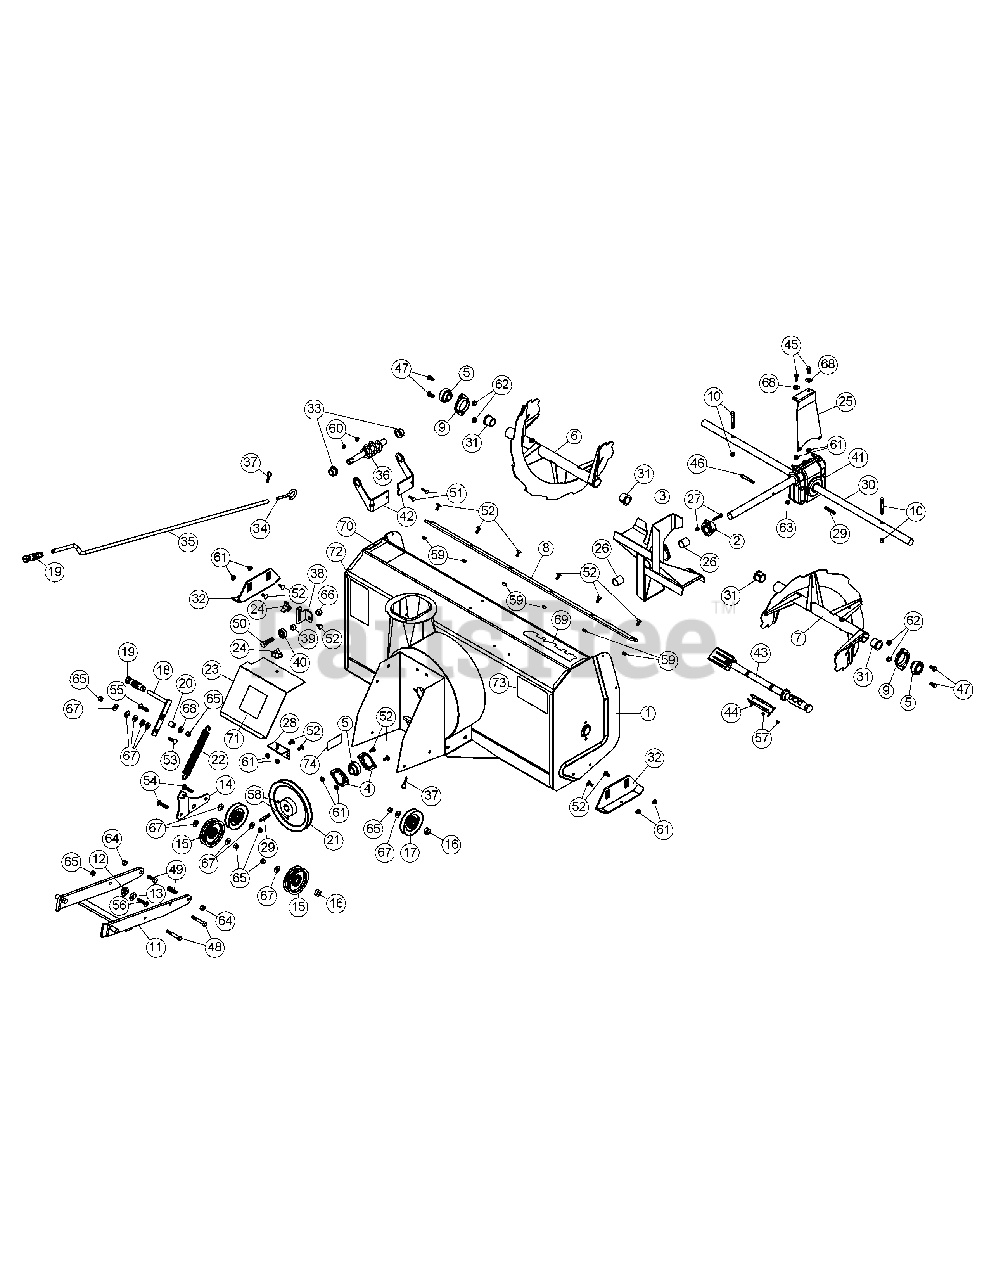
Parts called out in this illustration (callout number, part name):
1	Frame 44"
2	Shear plate
3	Fan
5	Bearing with set screw
6	Auger 44" left
7	Auger 44" right
8	Cutting edge 44"
10	Shear bolt / N.I.L.N. (auger)
11	Male hitch
12	Flange washer
13	Special washer
14	Tension lever
15	Flat pulley
18	Tension arm
25	Gear box support
26	Oil lite bushing
27	Shear bolt / N.I.L.N. (fan)
28	Belt guard support
29	Key 1/4" x 1/4" x 2"
31	Rotation bushing
33	Rotation bushing
34	Handle hook
36	Rotation worm
37	Hair pin 2.5mm
41	Gear box left rotation
42	Worm supports
43	Chute shovel
44	Chute shovel support
45	Hex. bolt 5/16" n.c. x 3/4" GR5
46	Hex. bolt 5/16" n.c. x 2 1/4" GR8
47	Hex. bolt 3/8" n.c. x 3/4" GR5
48	Hex. bolt 3/8" n.c. x 2 1/2" GR5
49	Hex. bolt 7/16" n.c. x 1 1/4" GR5
50	Hex. bolt 1/2" n.c. x 1 3/4" GR5
51	Carriage bolt 1/4" n.c. x 1 " GR5
52	Carriage bolt 5/16" n.c. x 3/4 " GR5
53	Carriage bolt 3/8" n.c. x 1 1/4 " GR5
54	Carriage bolt 3/8" n.c. x 1 3/4 " GR5
55	Carriage bolt 3/8" n.c. x 1 1/2 " GR5
56	Hex socket f.h. cap screw 3/8" n.c. x 1-3/4"
57	Socket Head Cap Screw M5 x 0.80 x 10
58	Socket head set screw 5/16"' n.c. x 5/16''
59	Stover lock nut 5/16" n.c.
60	Flange nut 1/4" n.c.
61	Flange nut 5/16" n.c.
62	Flange nut 3/8" n.c.
63	Nylon Insert lock Nut 5/16" n.c. GR5
64	Nylon Insert lock Nut 7/16" n.c.
65	Nylon Insert lock Nut 3/8" n.c.
66	Nylon Insert lock Nut 1/2" n.c.
67	Flat washer 7/16" hole
68	Flat washer 3/8" hole
69	Decal Cub Cadet
70	Decal danger auger
71	Decal danger belts
72	Decal read instructions
73	Decal warning safety
